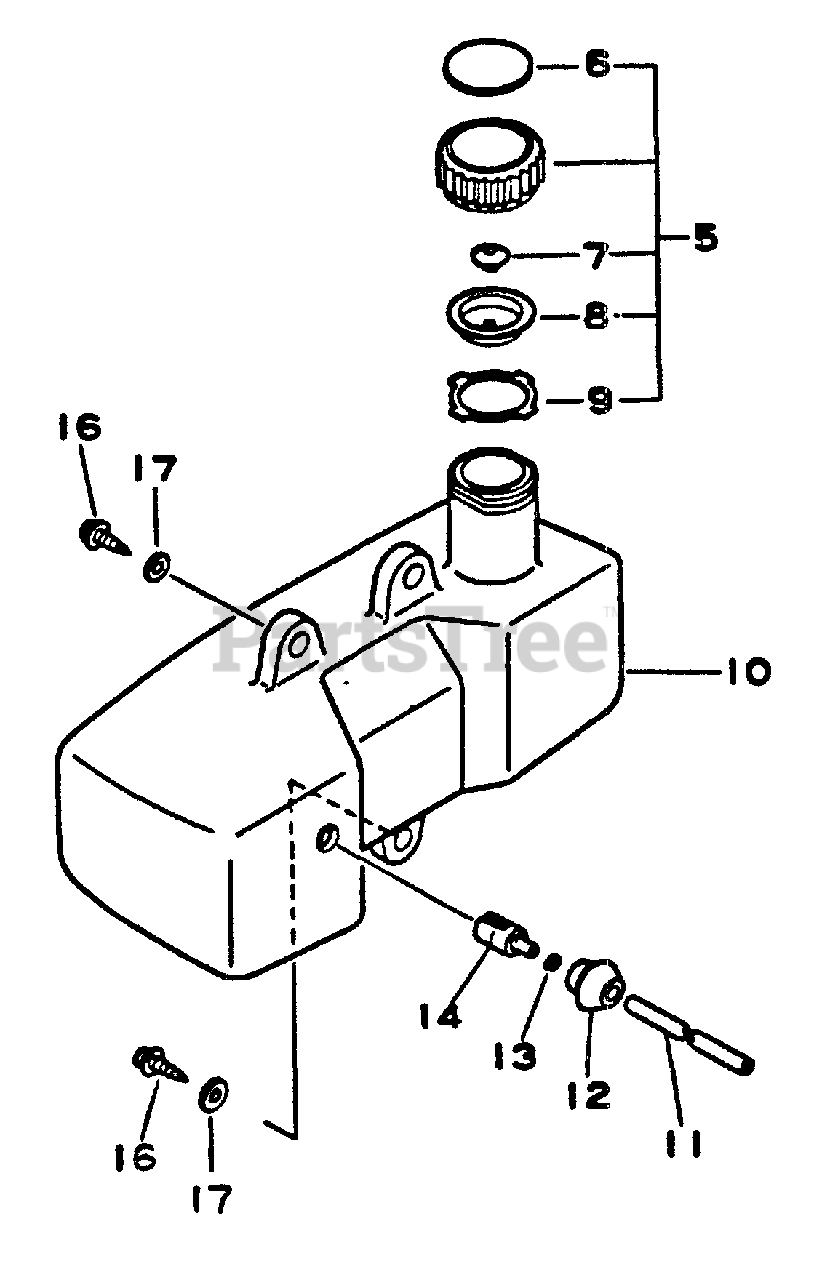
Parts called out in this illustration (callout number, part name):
5	CAP ASSY
6	LABEL - FUEL MIX
8	HOLDER, VENT
9	GASKET, CAP
10	TANK, FUEL
11	PIPE - 3X5X210 -- BLACK
13	CLIP - 6
14	FILTER, FUEL
16	SCREW - 5X14
17	WASHER - 5
18	BRACKET, SWITCH
19	IGNITION SWITCH KIT
